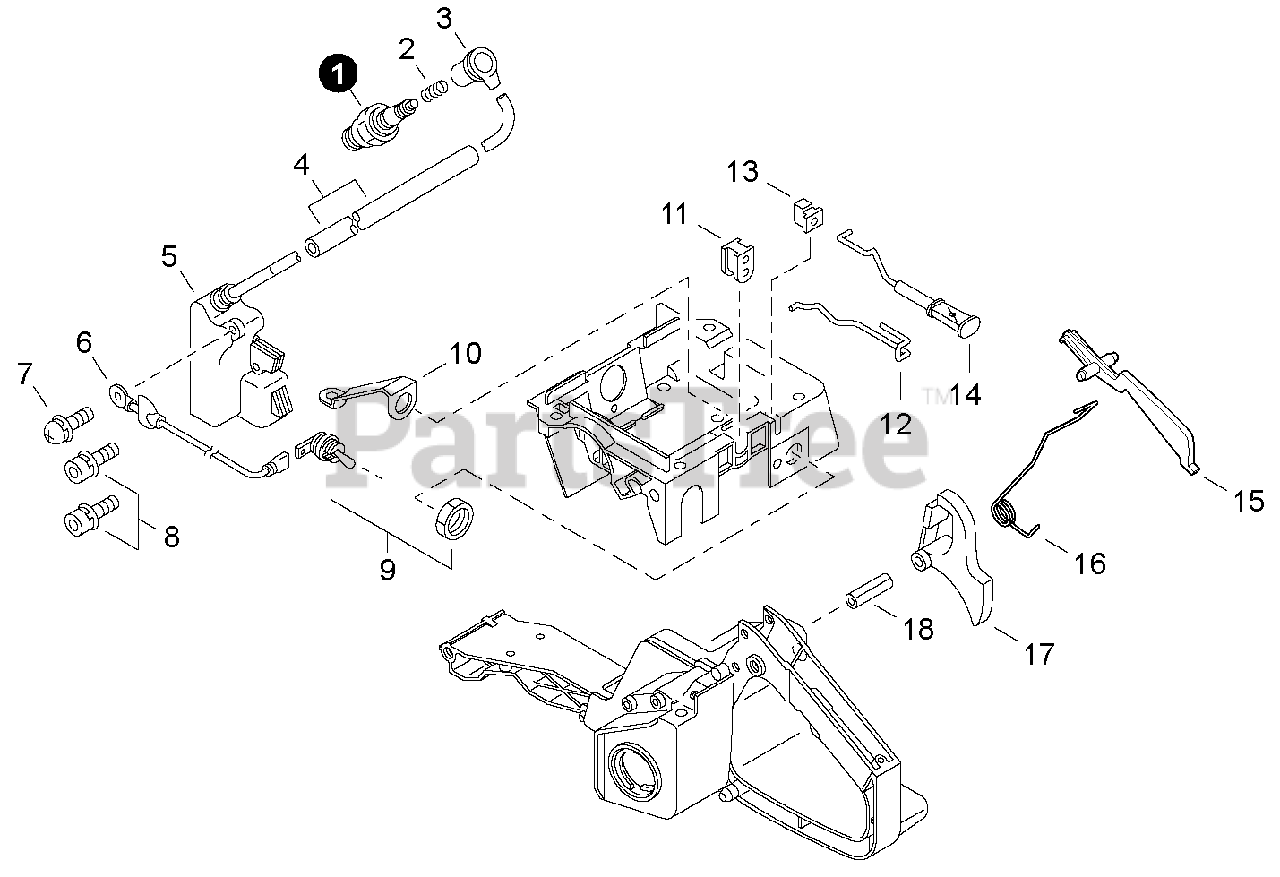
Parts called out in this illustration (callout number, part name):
1	SPARK PLUG - BPM7A
2	TERMINAL, SPARK PLUG
3	CAP, SPARK PLUG
5	COIL, IGNITION
7	SCREW 4×8
8	BOLT 4×20
9	SWITCH, ON-OFF
10	PLATE, GROUND
11	GROMMET, THROTTLE ROD
12	ROD, THROTTLE
13	GROMMET, CHOKE
14	ROD, CHOKE
15	LEVER, THROTTLE LOCKOUT
16	SPRING, THROTTLE RETURN
17	TRIGGER, THROTTLE
18	PIN, SPRING Ø5×25 MM
